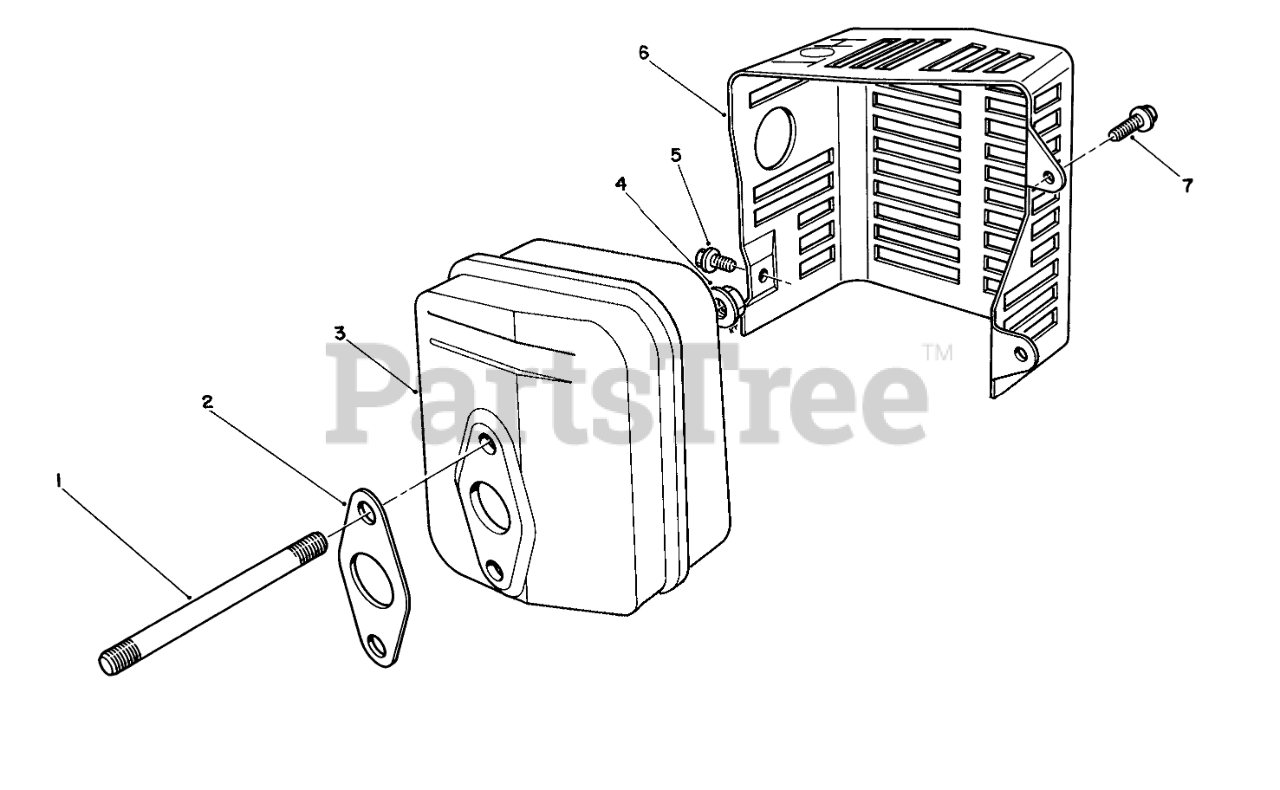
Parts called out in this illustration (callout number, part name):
2	GASKET
3	MUFFLER
5	SCREW
6	COVER
